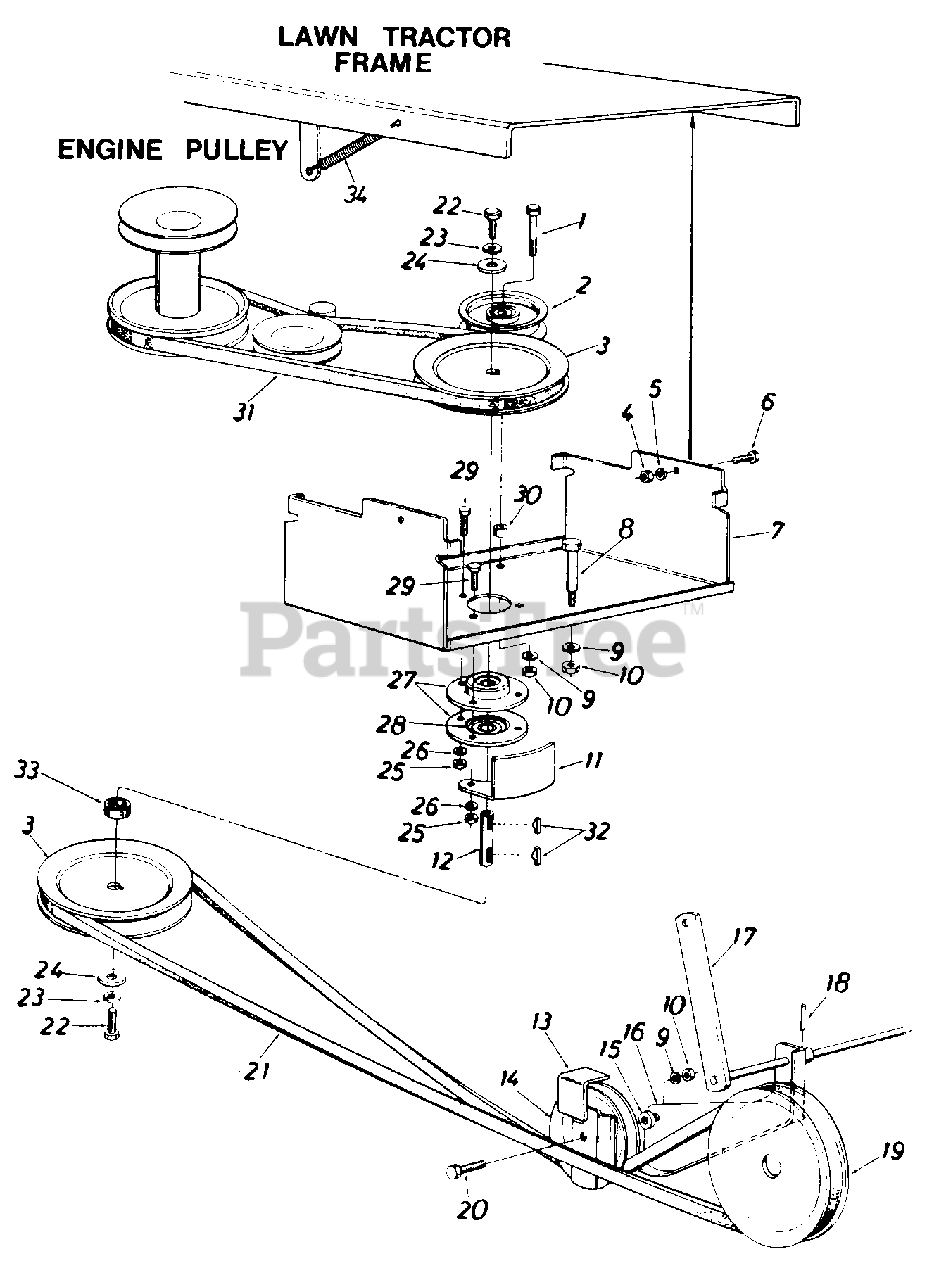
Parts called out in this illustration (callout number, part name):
1	Hex Bolt 3/8-16 x 2n Lg.
2	FL-Idler w/Flanges 3-3/4" O.D.
3	5/8" "V"-Pulley 79" I.D. x 65" O.D.
4	Hex Nut 3/8-24 Thd.
5	L-Wash. 3/8" I.D.
6	Hex Bolt 3/8-24 x .88" Lg.
9	L-Wash. 3/8" I.D.
10	Hex Nut 3/8-16 Thd.
13	Belt Separator Plate
14	Fl-Idler w/Flanges 3 25"
15	Fl-Wash. 406" I.D. x 1.25"
18	Spring Pin Roll 3/16" Dia.
19	5/8" V-Pulley 1.50" I.D. x 6.5" O.D.
20	Hex Bolt 3/8-16 x 1.75" Lg.
21	"V"-Belt
22	Hex Bolt 5/16-18 x .88" Lg. Spec.
23	L-Wash. 5/16" I.D.
24	Fl-Wash. .344" I.D. x 1.125"
25	Hex Nut 5/16-18 Thd.
26	L-Wash. 5/16" I.D.
27	Bearing Housing 1.85" I.D.
28	Ball Bearing 1.85" O.D.
29	Hex Sems Bolt 5/16-18 x .75"
30	Spacer
31	Belt
32	Hi-Pro Key 3/16" x 5/8"
33	Spacer .66" I.D. x 1" O.D.
34	Extension Spring
